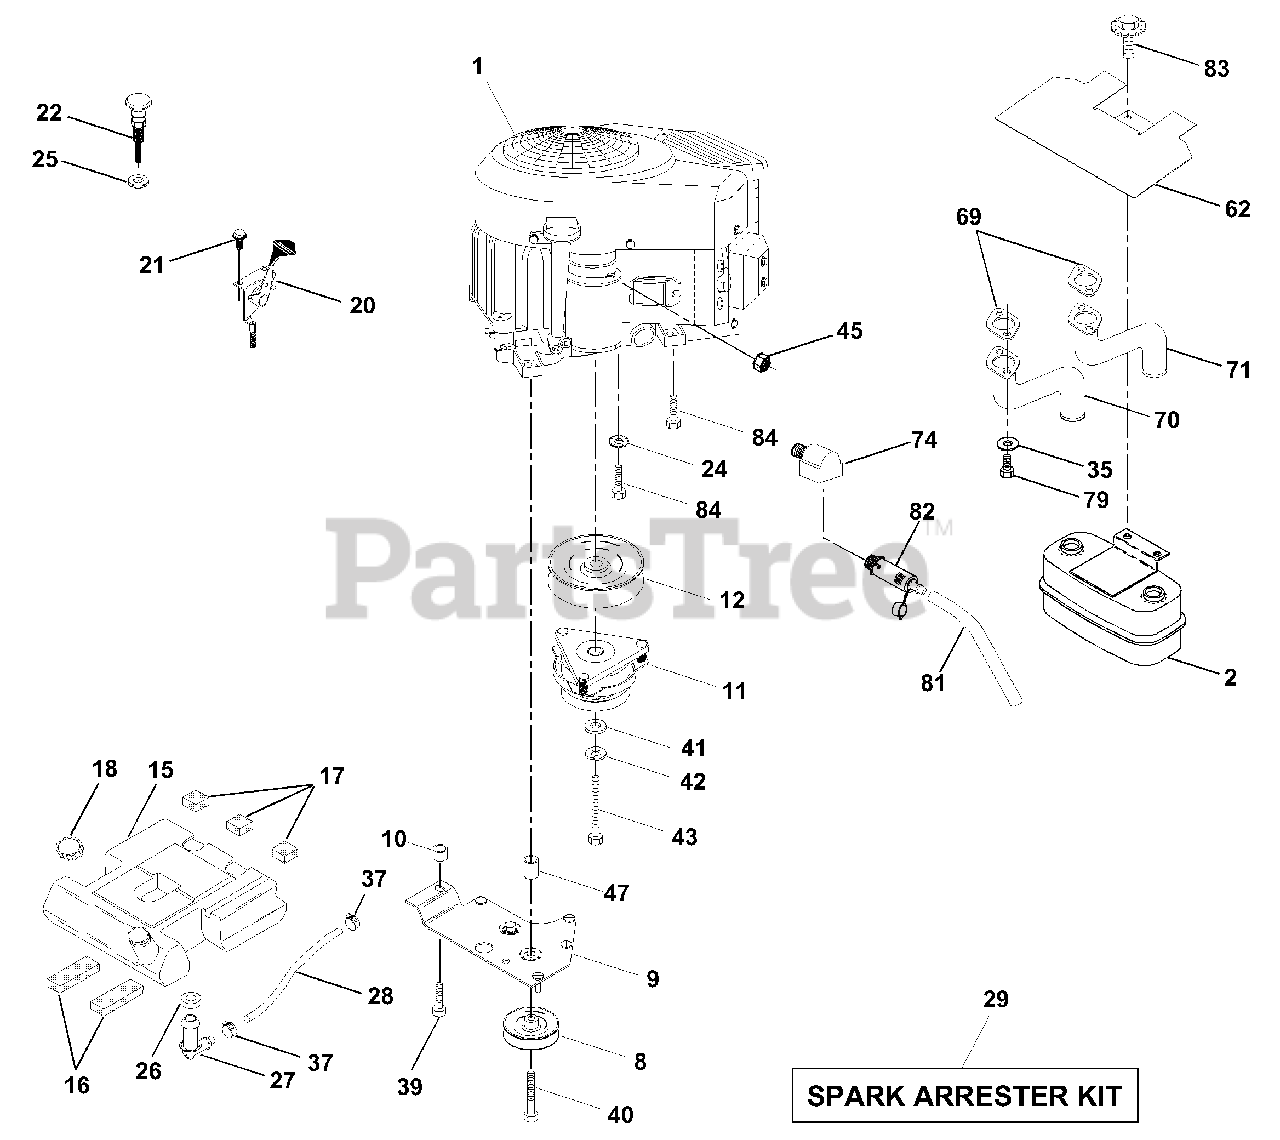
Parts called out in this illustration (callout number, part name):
2	Muffler
8	Pulley V-Idler
9	Keeper Asm Belt Engine Vgt
10	Bushing
11	Clutch Electric
12	Pulley Engine Grnd Drive
15	Tank Fuel Rear 3.50 YT/GT
16	Pad Spacer
17	Pad Spacer
18	Cap Asm Fuel Top Vent N/Lany
20	Control Throttle
21	Screw HWHD Hi-Lo #13-16 x 3/4
22	Control Choke
24	Lockwasher Ext Tooth 3/8
25	Nut Keps 3/8-24 UNF
26	Bushing
27	Stem Tank Fuel
29	Spark Arrester Kit
35	Washer Lock Hvy HLCL Spr. 5/16
37	Clamp Hose
39	Screw 3/8 - 16 x 2-1/4 UNC TT
40	Screw 3/8 - 16 x 4 UNC TT
41	Washer 1-1/2 OD X 15/32 ID X .250
42	Washer Lock 7/16
43	Bolt Hex 7/16-20 x 4 Gr. 5-1.5 Thr.
45	Nut Keps Hex 1/4-20 Unc
47	Bushing
62	Shield Heat Muffler
69	Gasket Muffler
70	Tube Exhaust LH
71	Tube Exhaust RH
74	Elbow Street Brass
79	Screw Hex Hd Cap 5/16-18 x 3/4
81	Tube Drain Oil Easy
82	Plug Oil Drain Easy
83	Bolt 5/16-18 Unc x 3/4 w/Sems
84	Screw Thdrol 3/8-16 x 1-1/2
